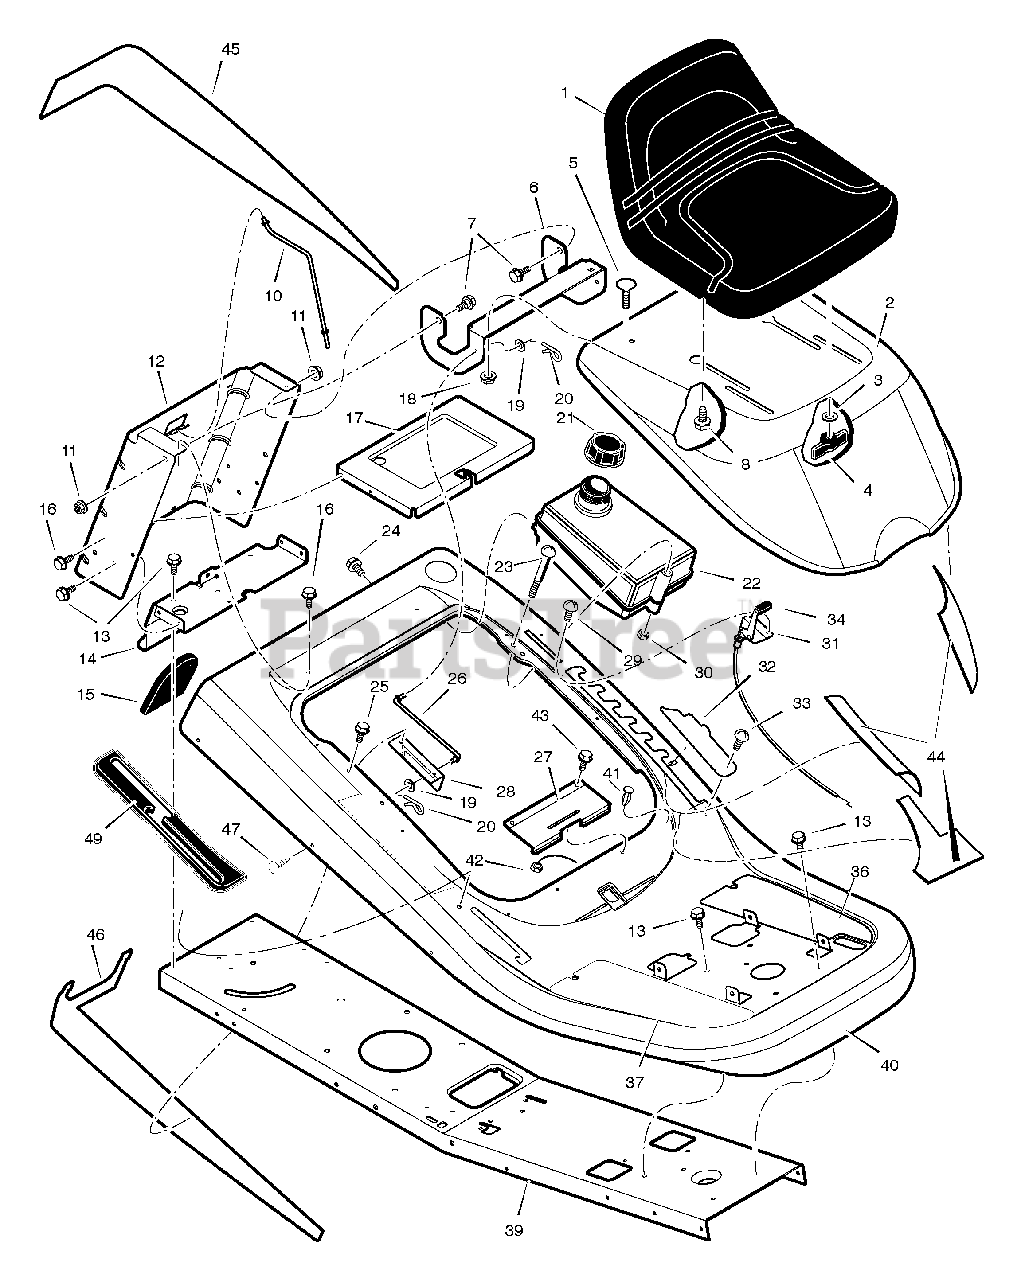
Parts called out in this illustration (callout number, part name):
1	Seat
2	Hood
3	Washer
4	Bolt, Wing
5	Bolt, Carriage
6	Bracket, Hinge
7	Bolt, Shoulder
8	Bolt, Shoulder
10	Rod, Battery
11	Nut, Flange
12	Plate, Rear
14	Plate, Hitch
17	TRAY, Battery
18	Nut, Flange
19	Washer
20	Pin, Hair
21	Cap, Fuel Tank
22	Tank, Fuel
23	Screw
26	Rod, Hood Prop
27	Spring, Seat Deck
28	Bracket, Prop Rod
30	Nut, NY-Lock
31	Control, Throttle
32	Cover, Detent (Black)
33	Bolt, Shoulder
36	Footmat, Left (Black)
37	Footmat, Right (Black)
40	Deck, Seat
41	Bumper
42	Nut
43	Screw
44	Kit, Foil Heat Shield
45	Trim, Left
46	Trim, Right
47	Fastener, Panel
49	Cover, Long Black
